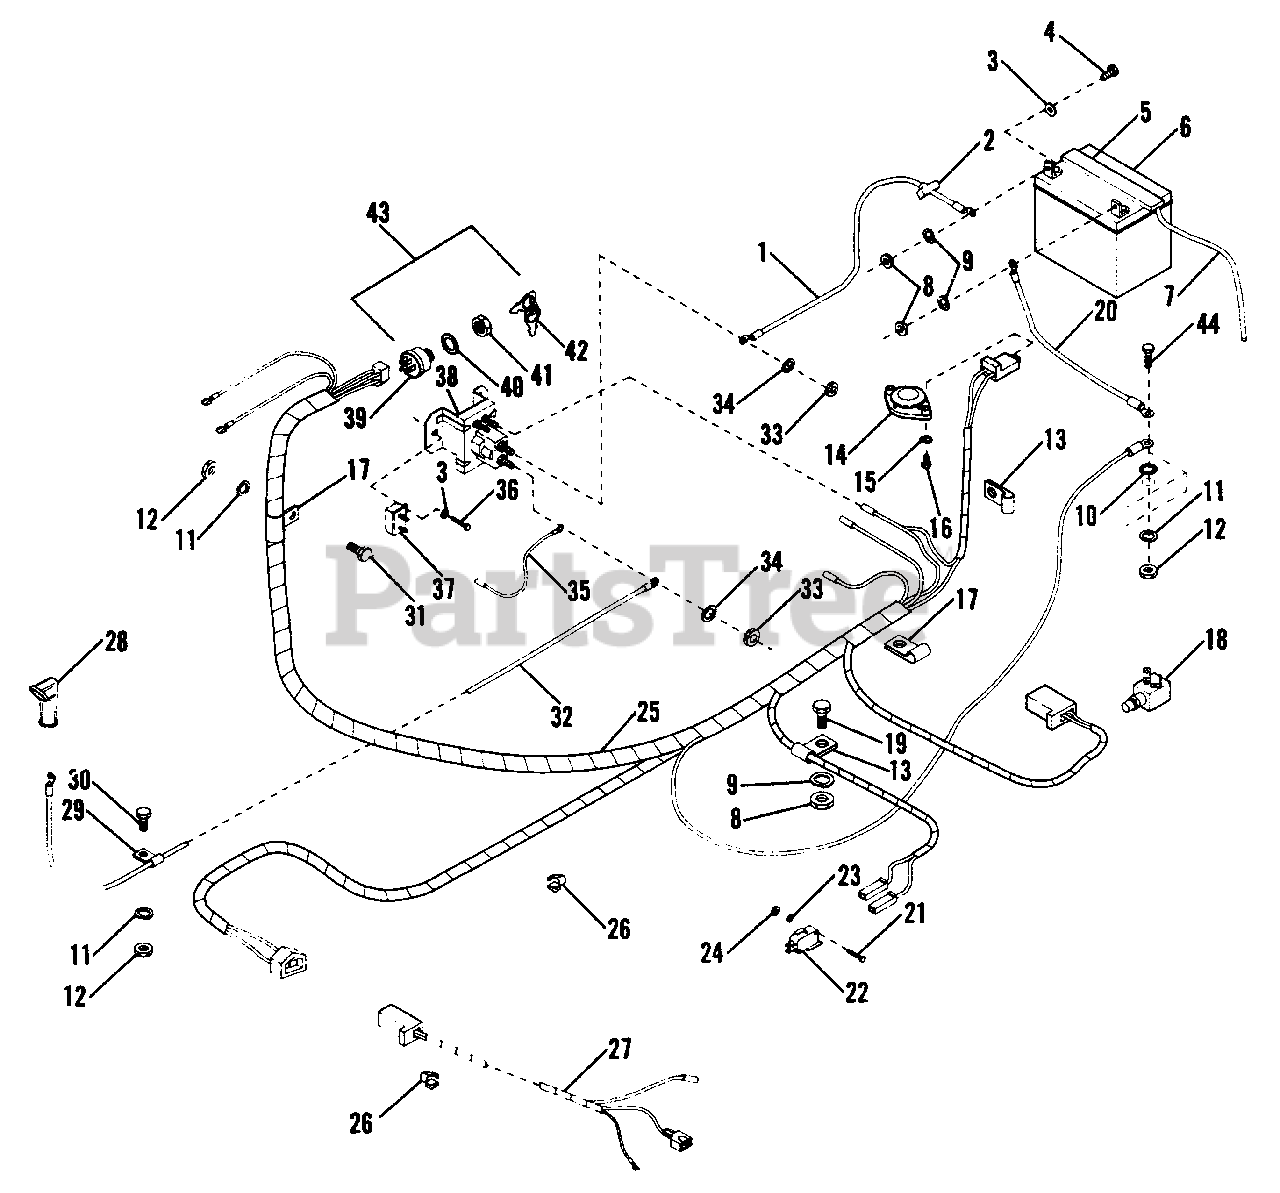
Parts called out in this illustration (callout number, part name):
1	WIRE ASSY., Battery to Solenoid
2	BOOT, Insulator
3	WASHER, Plain
4	CAPSCREW, Hex 1/4-20 x 3/4
5	VENT CAP, Battery
7	HOSE, Drain, Battery
8	NUT, Hex 1/4-20
9	LOCKWASHER, Spring 1/4
10	LOCKWASHER, External Tooth 5/16
11	LOCKWASHER, Spring 5/16 (1691843, 1691845) LOCKWASHER, Spring 5/16 (1691841)
12	NUT, Hex 5/16-18
14	SWITCH ASSY., Safety, Seat
15	LOCKWASHER, External Tooth 1/4
16	SCREW, Round Head 1/4-20 x 3/4
18	SWITCH, Interlock, PTO
19	CAPSCREW, Hex 1/4-20 x 5/8
20	WIRE ASSY., Battery to Engine Ground (1691841)
20	WIRE ASSY., Battery to Engine Ground (1691843, 1691845)
21	CAPSCREW, Hex #5-40 x 3/4
22	MICROSWITCH, Interlock
23	LOCKWASHER, Spring #5
24	NUT, Hex #5-40
25	HARNESS ASSEMBLY, Lever Steer
26	CLIP (1691841)
27	WIRE ASSY., Harness to Engine (1691841)
29	CLAMP, Wire (1691841)
30	CAPSCREW, Hex 5/16-18 x 3/4 (1691841)
31	CAPSCREW, Hex 5/16-18 x 1
32	WIRE ASSY., Solenoid to Starter (1691841)
32	WIRE ASSY., Solenoid to Starter (1691843, 1691845)
33	NUT, Hex 5/16-24
34	LOCKWASHER, Spring 5/16
35	WIRE, Circuit Breaker to Solenoid
36	SCREW, Taptite 1/4-20 x 5/8
37	CIRCUIT BREAKER
38	SOLENOID
39	SWITCH, Ignition (See Ref. No. 43)
40	LOCKWASHER, Internal Tooth 5/8
41	NUT, Hex 5/8-32
42	KEYS & RING
43	IGNITION SWITCH ASSY. (Incl. Ref. Nos. 39-42)
44	CAPSCREW, Hex Head 5/16-18 x 2 G5
